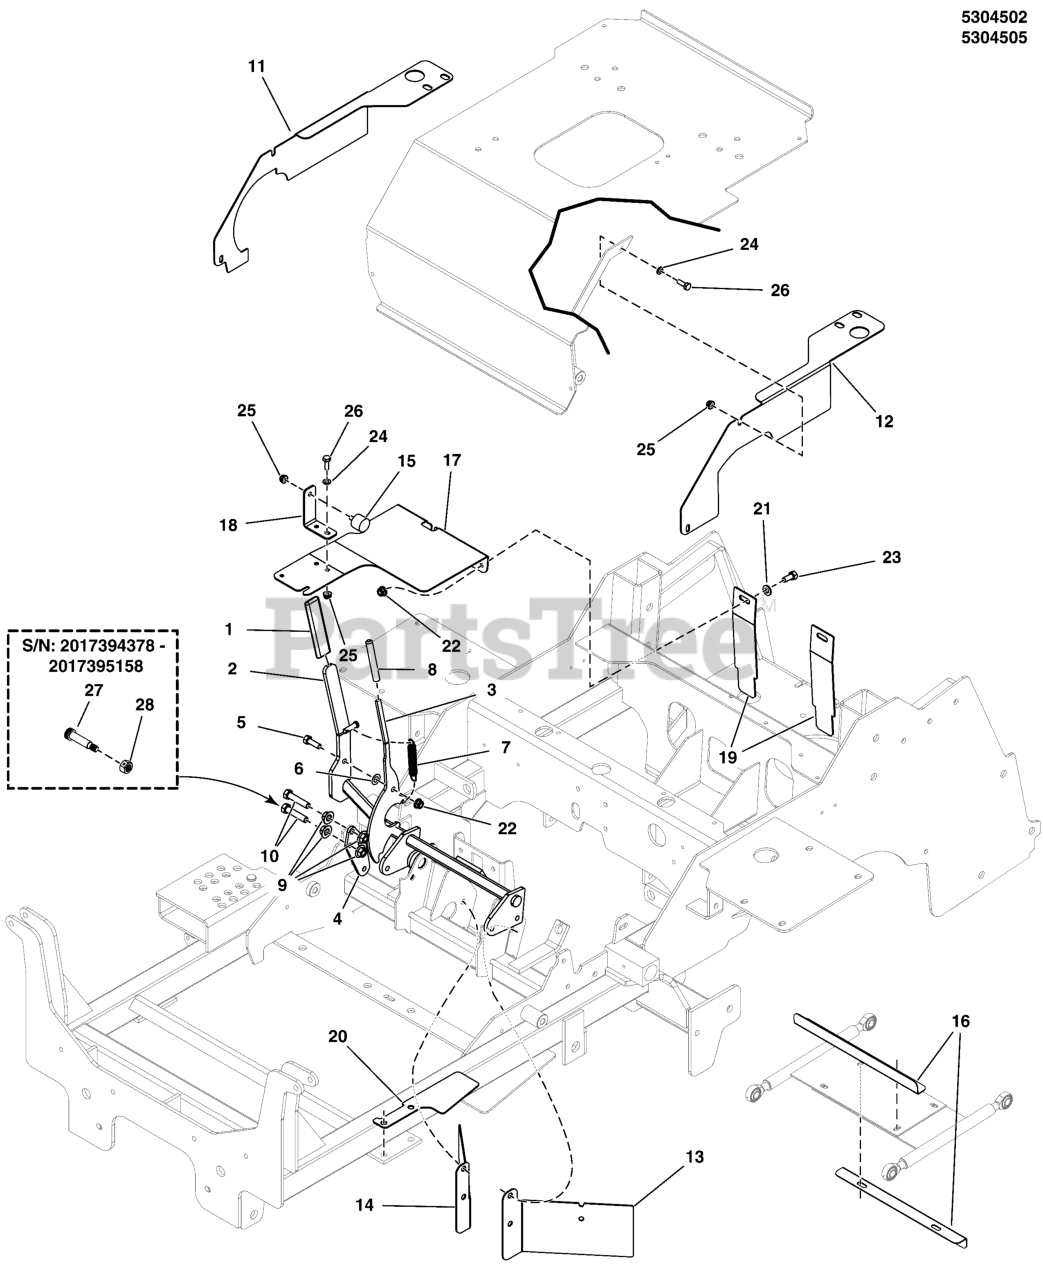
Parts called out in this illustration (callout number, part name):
1	GRIP, FOAM, 1/4 X 1 X 4.1
2	WELD, HANDLE, BRAKE, IS2100 CE - BLK
3	LEVER, BRAKE, IS2600 EU - BLK
4	PLATE, PIVOT MOUNT, BRAKE,IS2600 EU, RED
5	SCREW, TRUSS HD TORX DR5/16-18X0.875 BLK
6	WASHER,WAVE,M10
7	SPRING-EXT, .500 OD X 3.50 LG X .058 WR
8	COVER, VINYL HANDLE
9	NUT, 3/8-16 HEX SERRATED FLANGE
10	BOLT, 3/8-16 X 1-3/4" GD5 CZ
11	PLATE, GUARD, SEAT PLATFORM, RH - RED
12	PLATE, GUARD, SEAT PLATFORM, LH - RED
13	PLATE, GUARD, CRADLE, LH - BLK
14	PLATE, GUARD, CRADLE, RH - BLK
15	BUMPER, RUBBER 1/4-20
16	PLATE, GUARD, PULLER BAR,IS2600Z EU, BLK
17	PLATE, FAN COVER, RH - BLK
18	PLATE, BRACKET, SEAT LOCK - BLK
19	PLATE, COVER, TRANSMISSION - BLK
20	PLATE, DECK SHIELD, FRAME - LH - RED
21	WASHER, 5/16" SAE
22	NUT, 5/16-18 HEX NYLOCK FLANGE
23	BOLT, 5/16-18 X 3/4 GD5
24	WASHER, 1/4 SAE
25	NUT, 1/4-20 HEX NYLOCK FLANGE
26	BOLT, 1/4-20 X 3/4 GD5 CZ
27	BOLT, 5/16-18, 3/8 X 1-1/4 SHOULDER
28	NUT, 5/16-18, HEX, CNTR LK, ZINC PHOS/OIL
